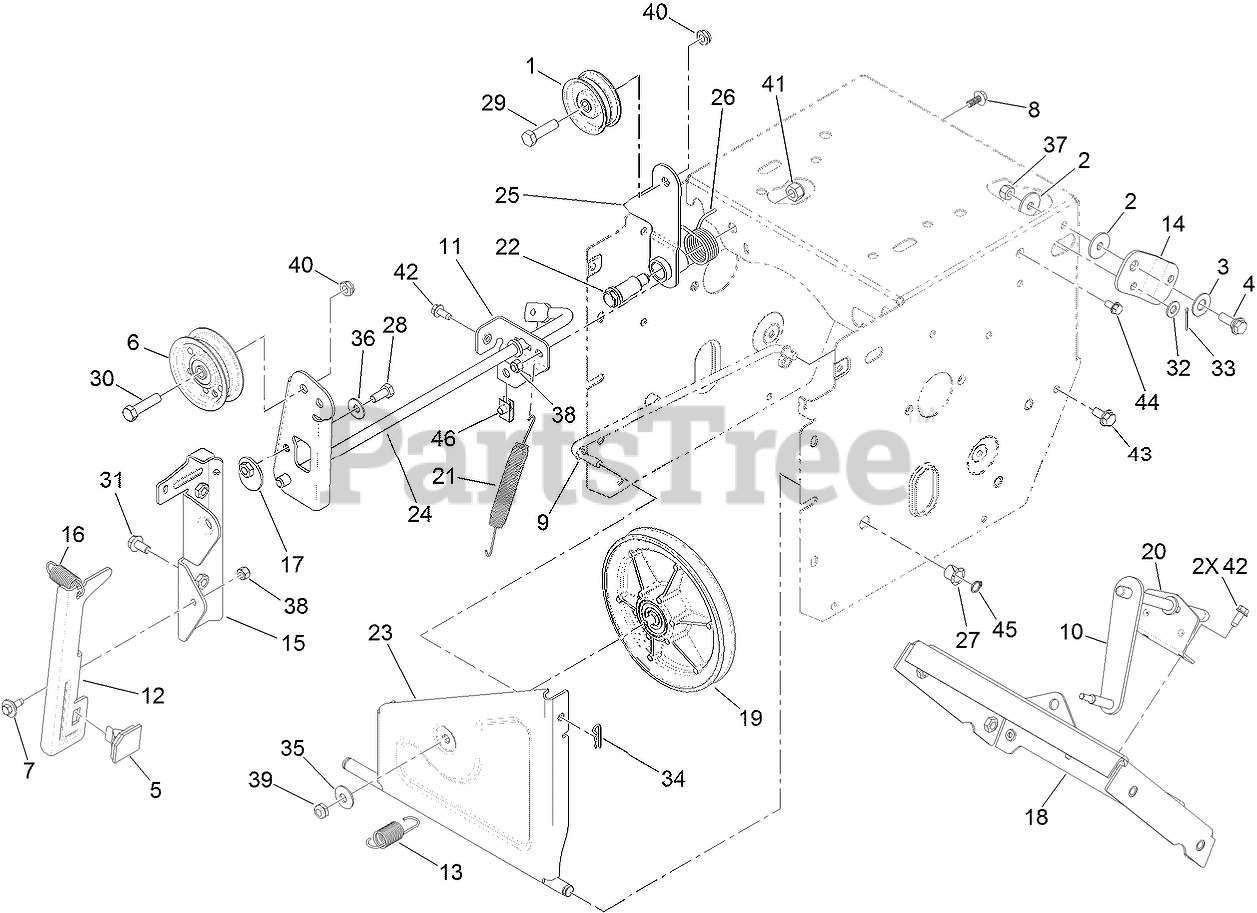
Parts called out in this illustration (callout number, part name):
1	PULLEY-IDLER
2	WASHER-PIVOT
3	WASHER
4	SCREW-SHOULDER
5	PAD-BRAKE
6	PULLEY-IDLER
7	SCREW-SHOULDER
8	SCREW-HHF
9	LINK-CONTROL, SPEED
10	LEVER-CONTROL, TRACTION
11	BRACKET-CLUTCH, IMPELLER
12	ARM-BRAKE
13	SPRING-EXTENSION
14	BELLCRANK-DRIVE
15	BRACKET-IDLER, IMPELLER
16	SPRING-EXTENSION
18	SHIFT PLATE ASM
19	PULLEY-TRACTION
20	BRACKET-ROD, SHIFT
21	SPRING-EXTENSION
22	BOLT-SHOULDER
23	BRACKET-WHEEL, FRICTION
24	IMPELLER CLUTCH ASM
25	TRACTION IDLER ARM
26	SPRING-TORSION
27	BUSHING-NYLINER
28	SCREW-HH
29	SCREW-HH
30	SCREW-HH
31	SCREW-HHF
32	WASHER-PLAIN
33	PIN-COTTER
34	PIN-COTTER
35	WASHER-BELLEVILLE
36	WASHER-BELLEVILLE
37	NUT-LOCK, NI
38	NUT-LOCK, NI
39	NUT-HEX
40	NUT-LOCK, NI
41	NUT-LOCK, NI
42	SCREW-HWH
43	SCREW-HWHTF
44	SCREW-HWH
45	RING-RETAINING
